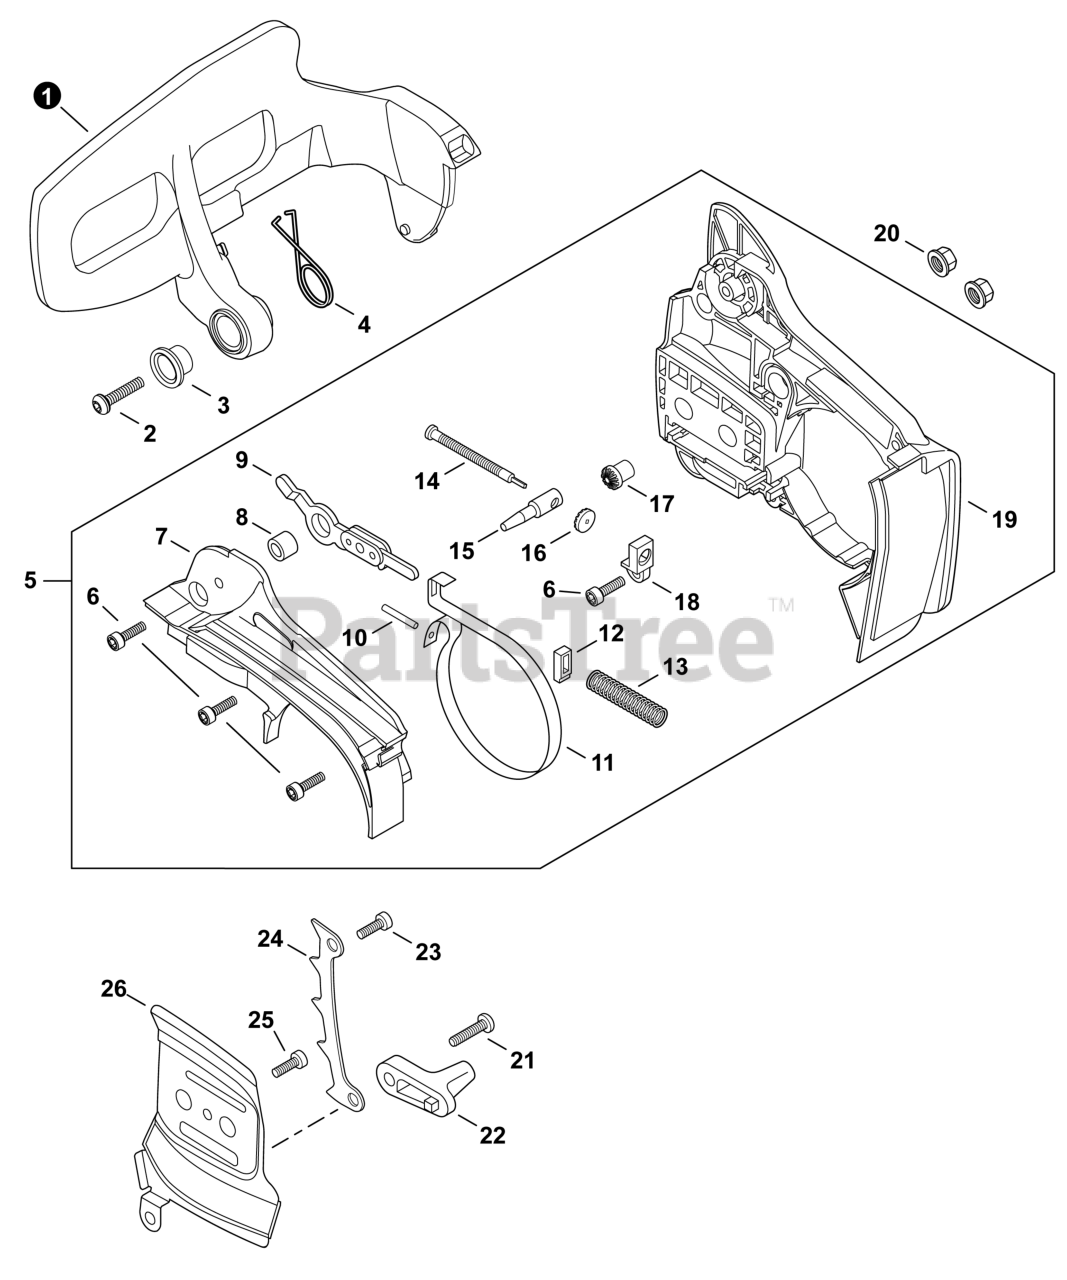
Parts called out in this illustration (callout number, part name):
1	LEVER, BRAKE
2	BOLT, TORX 5x12
3	COLLAR 10
4	SPRING, TORSION
5	SPROCKET GUARD ASSY
6	BOLT, TORX 4x12
7	COVER, BRAKE
8	SPACER 8x12x9
9	CONNECTOR, BRAKE
10	PIN, SPRING 3x9.8
11	BAND, BRAKE
13	SPRING, COMPRESSION
15	TENSIONER, CHAIN
16	GEAR, BEVEL
17	GEAR, BEVEL
18	COLLAR 8
19	GUARD, SPROCKET
20	NUT, FLANGE M8x1.25
21	BOLT, TORX 5x20
22	CATCHER, CHAIN
23	BOLT, TORX 5x20
24	SPIKE, BUMPER
25	BOLT, TORX 4x12
26	PLATE, GUIDE - INNER
